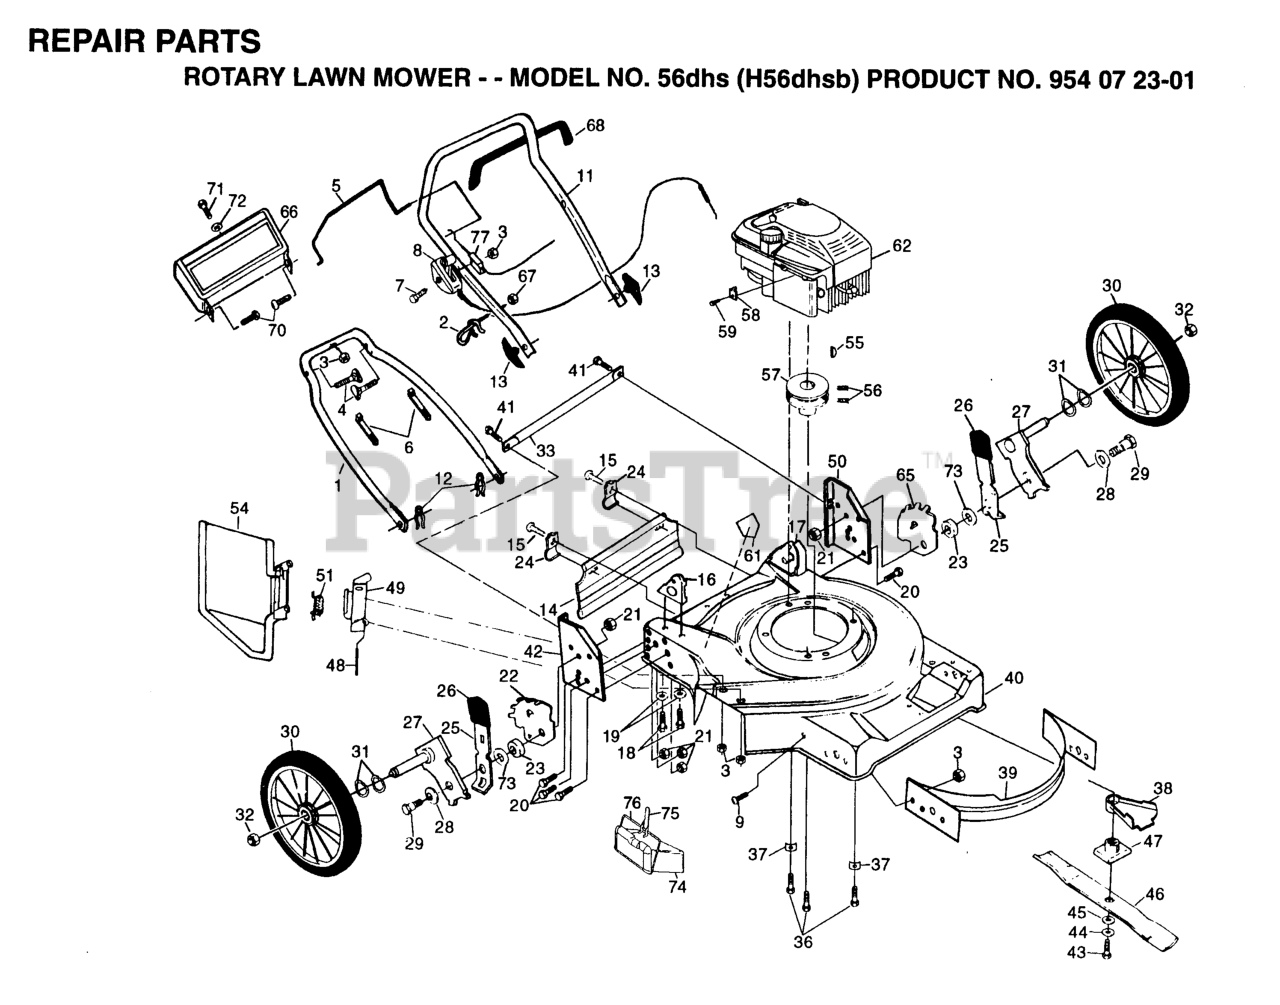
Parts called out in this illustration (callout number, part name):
1	HANDLE, LOWER PM
2	ROPE GUIDE
3	NUT
4	HANDLE BOLT
5	CONTROL BAR
6	TIE GUIDE
7	SCREW 1/4-20 X 2.12
8	THROTTLE CONTROL
10	SELF-TAPPING SCREW
11	UPPER HANDLE
12	HAIRPIN COTTER
13	HANDLE KNOB
14	SKIRT.REAR.22SD.WALK
15	TAPPING SCREW
16	HANDLE BRKT ASSY RH
17	HANDLE BRKT ASSY LH
18	SCREW
19	STEEL WASHER
21	LOCKNUT PM
22	WHL ADJ BRKT LF/RR
23	SPACER PM
24	BRACKET DEFL PM
25	SELECTOR SPRING
26	SELECTOR KNOB
27	AXLE ARM ASSEMBLY (REAR)
28	WASHER
29	BOLT
30	WHEEL TIRE PM
31	WAVE WASHER
32	HEX FLANGE LOCKNT
33	ROD SUPPORT
36	BOLT
37	WASHER.ENGINE.BZP
38	DEBRIS SHIELD
39	FRONT BAFFLE
40	HOUSING ASMBLY
42	WHEEL SUPPORT BRACKET (LEFT)
43	SCREW, HEX HD 3/8-24 X 1-3/8
44	LOCKWASHER
45	WASHER,HARDEN
47	BLADE ADAPTOR
48	ROD.HINGE.COMBI-C
49	BRACKET.HINGE ASM.W/FIN
50	WHEEL SUPPORT BRACKET (RIGHT)
51	HINGE SPRING
55	HI PRO KEY PM WSL
57	ENGINE.PULLEY.FWG
58	WASHER
59	SCREW.HEX.HEAD.WASHER.10-16
61	DECAL HYT
65	WHL ADJ BRKT RF/LR
66	TRIM PLATE
67	NUT
68	HANDLE GRIP
71	SCREW
73	WASHER.FLAT.1/2
77	CABLE.MZR.51.RT.SP./PU.
